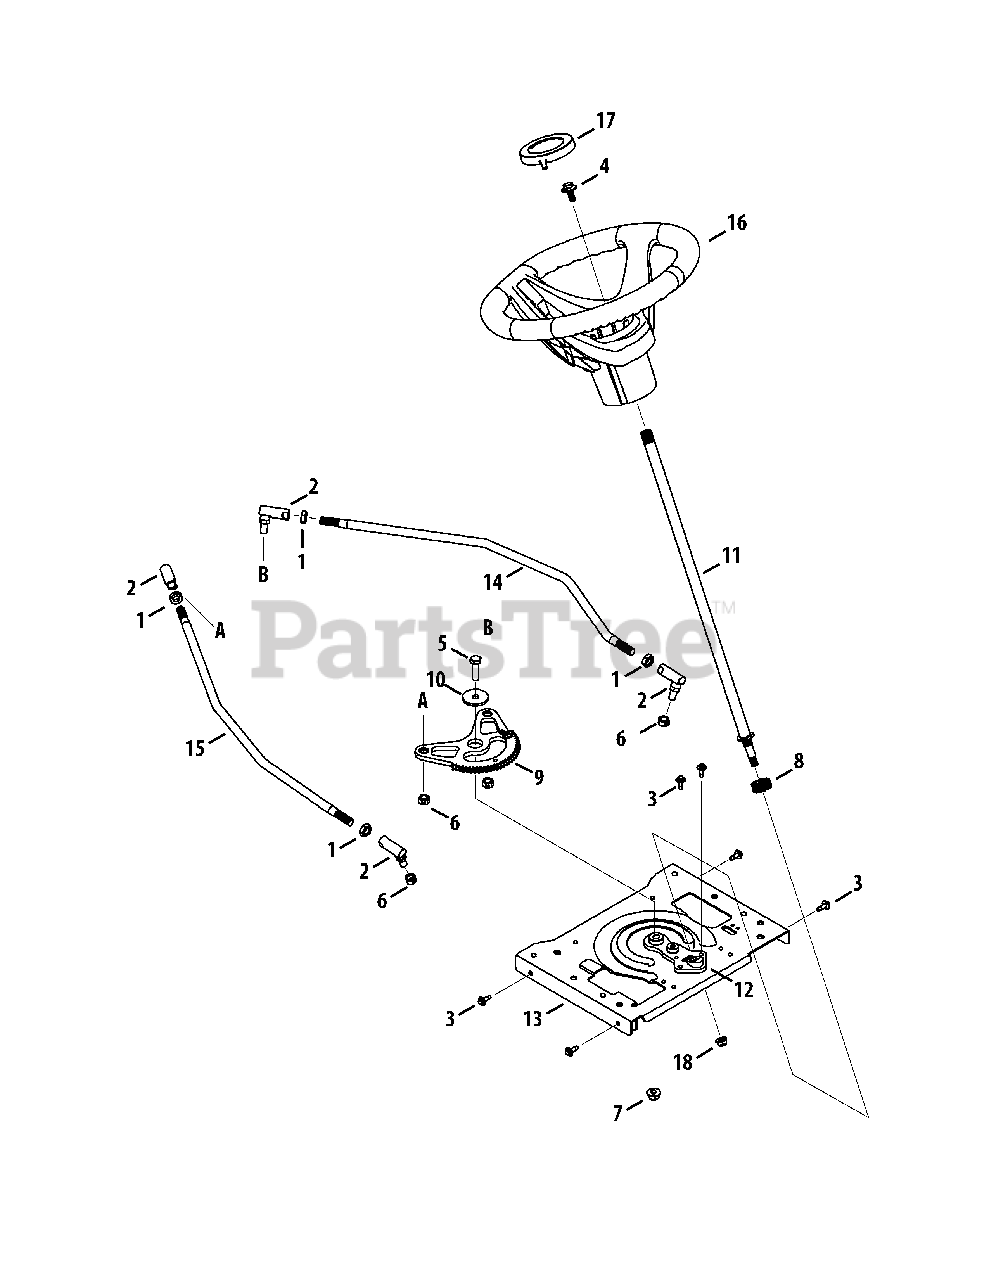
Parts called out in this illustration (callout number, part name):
1	Jam Nut, 7/16-20
2	Ball Joint, 7/16-20, Lock
3	Screw, M6-1 x .625
4	Screw, 5/16-24 x .850
5	Hex Cap Screw, 3/8-16 x 1.25
6	Nut, Hex Lock, 3/8-24, Grb
7	Nut, Flange Lock, 3/8-16, Grf,
8	Pinion Gear, 13T
9	Steering Gear
10	Flat Washer, .390 x 2.490 x .119
11	Shaft, Steering, .625 OD x 20
12	Steering Support
14	Steering Rod, LH
15	Steering Rod, RH
16	Steering Wheel
17	Cap, Steering Wheel
18	Nut, Flange Lock, 5/16-18, Grf
